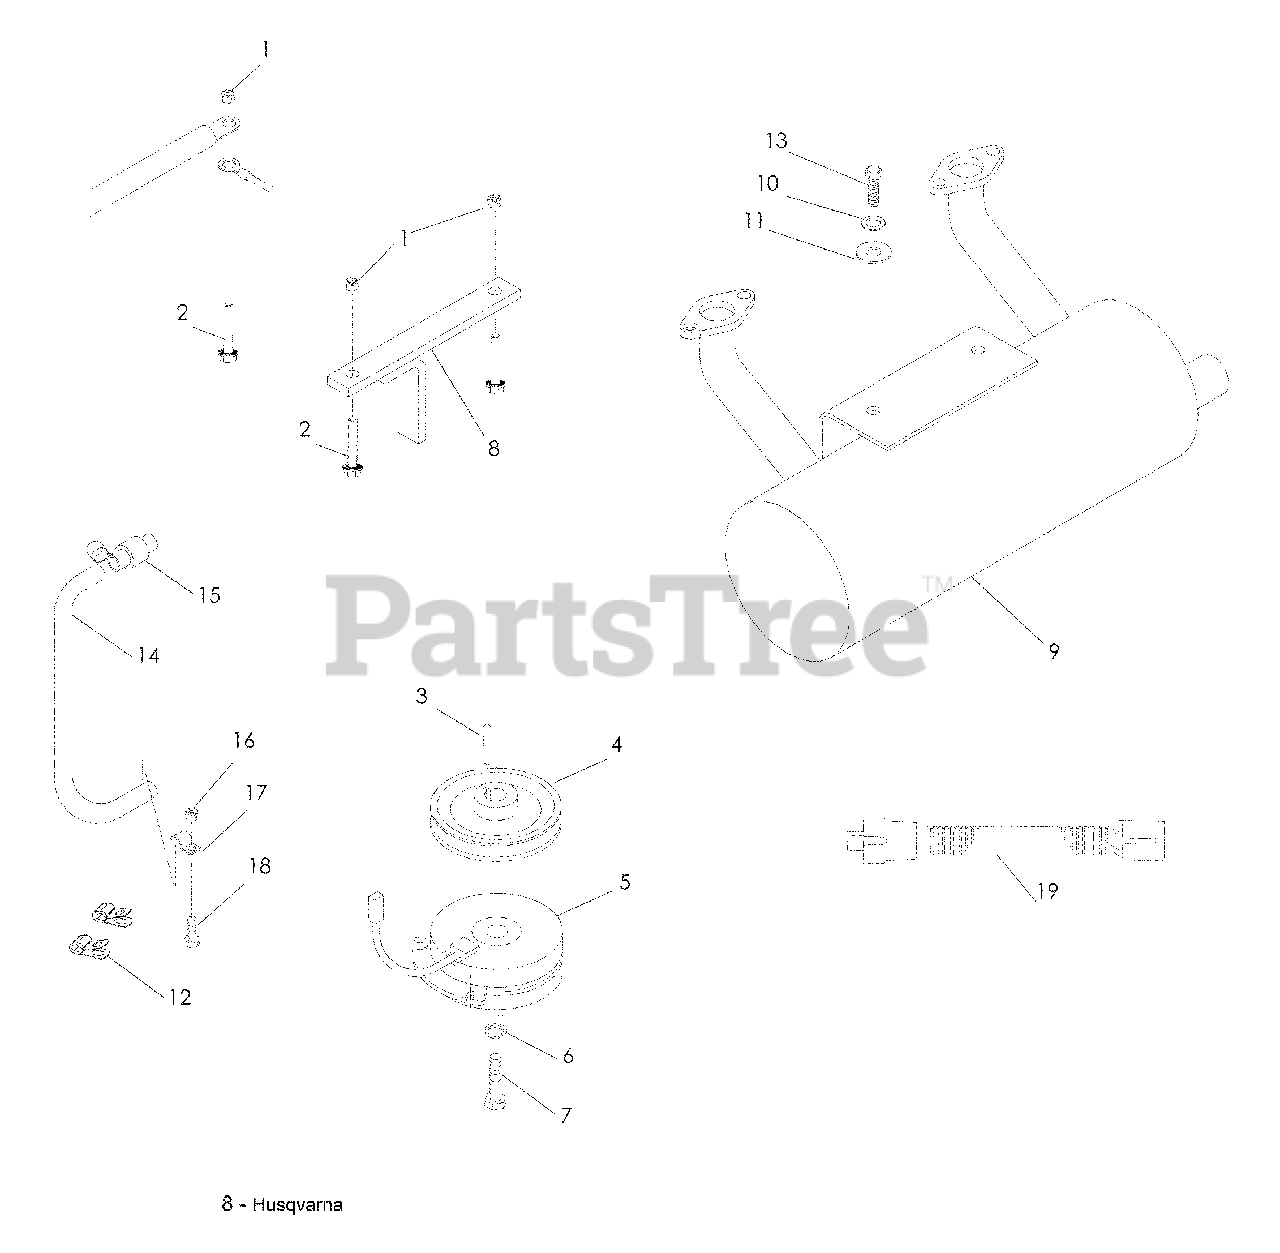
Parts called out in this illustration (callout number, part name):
1	NUT 5/16-18 CENTERLOCK
2	HCS 5/16 x 1¾ SERRATED
6	LOCKWASHER 7/16
7	HCS 7/16 x 2½
8	TIE DOWN, CLUTCH
10	LOCKWASHER 5/16
11	WASHER 5/16 STD FLT
12	CLAMP, DOUBLE TUBE
13	HCS 5/16-18 x ¾
14	OIL DRAIN HOSE
15	OIL DRAIN FITTING
16	NUT ¼-20 CENTERLOCK
18	HCS ¼- 20 x ¾
